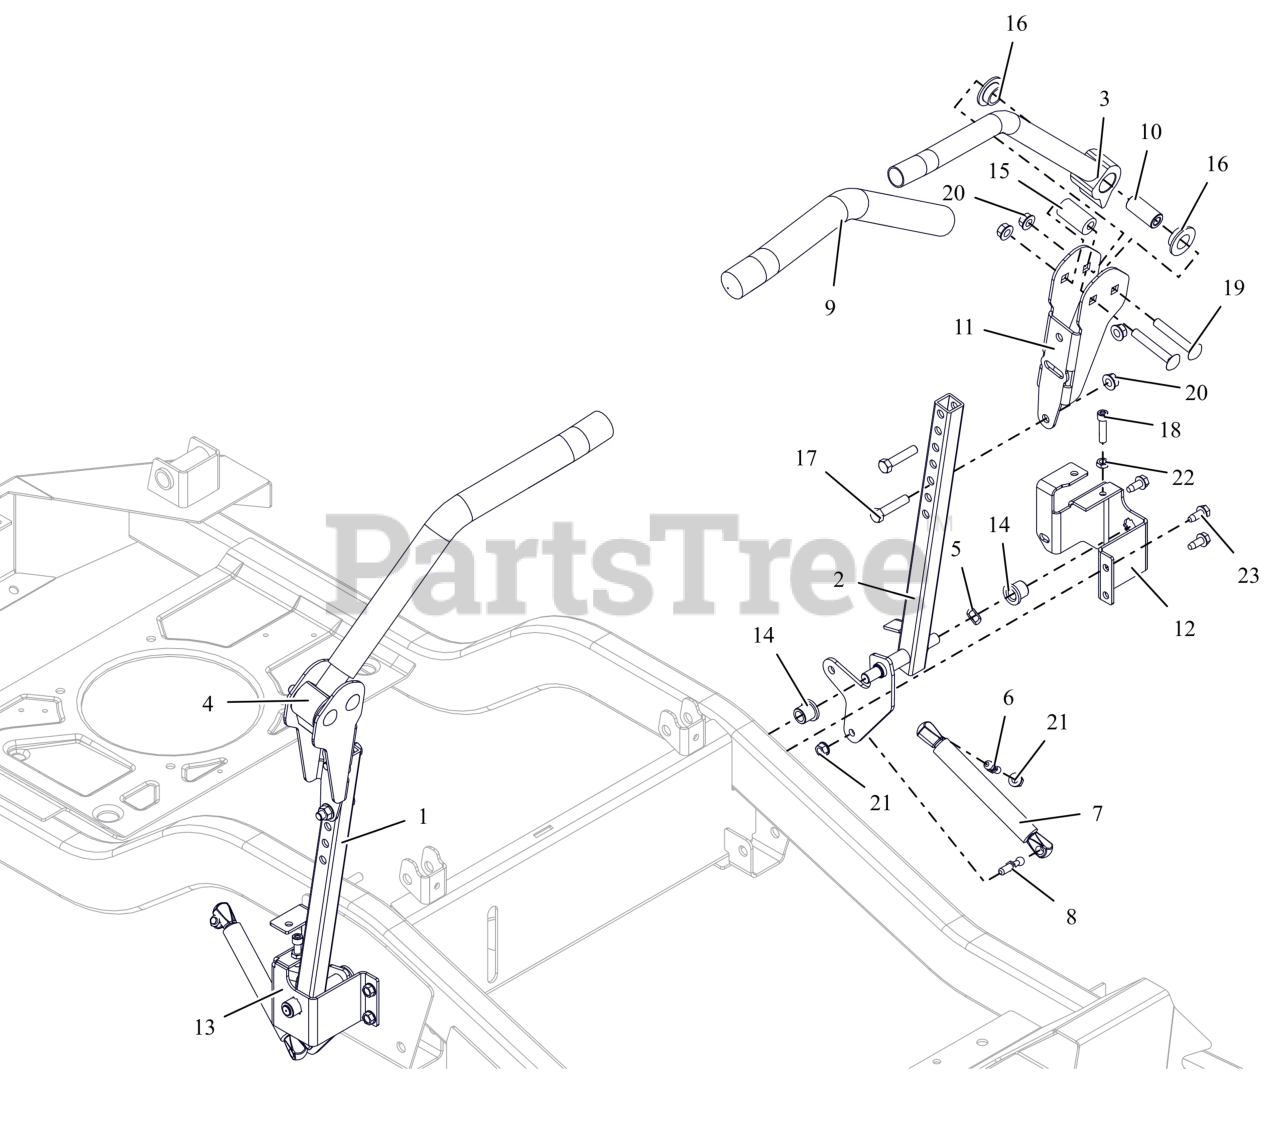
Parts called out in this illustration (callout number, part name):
1	WLDMT, STEERING RH
2	WLDMT, STEERING LH
3	WLDMT, CONTROL HANDLE-LH (BLACK)
4	WLDMT, CONTROL HANDLE-RH (BLACK)
5	WAVE WASHER .531X.781X.125FH
6	STUD- BALL
7	DAMPER
8	STUD-BALL-THREADED
9	GRIP, HANDLEBAR
10	SPACER, STEERING ARM
11	ADJ UPPER CONTROL ARM BRKT-BLK
12	BRKT, STEERING ARM MOUNT -LH
13	BRKT, STEERING ARM MOUNT -RH
14	BHSG-FLG .500X.750X.750X.125
15	BSHG, ECCENTRIC.406X.875X1.625
16	BSHG-FLG .762X1.48X.44 NYL
17	BLT, HEX .38-16X1.75 G5 ZCC
18	BLT, SHCS .312-18X1.25 G8 SS
19	BLT, RHSSN.38-16X2.50 G5 ZCC
20	NUT-LK-TOP-FLG .38-16 ZC120
21	NUT,LK-CTR-FLG .31-18 GF ZCC
22	NUT-JAM .312-18 G2 ZCC
23	SCR,TAP .312-18X.75 HWH TR ZCC
